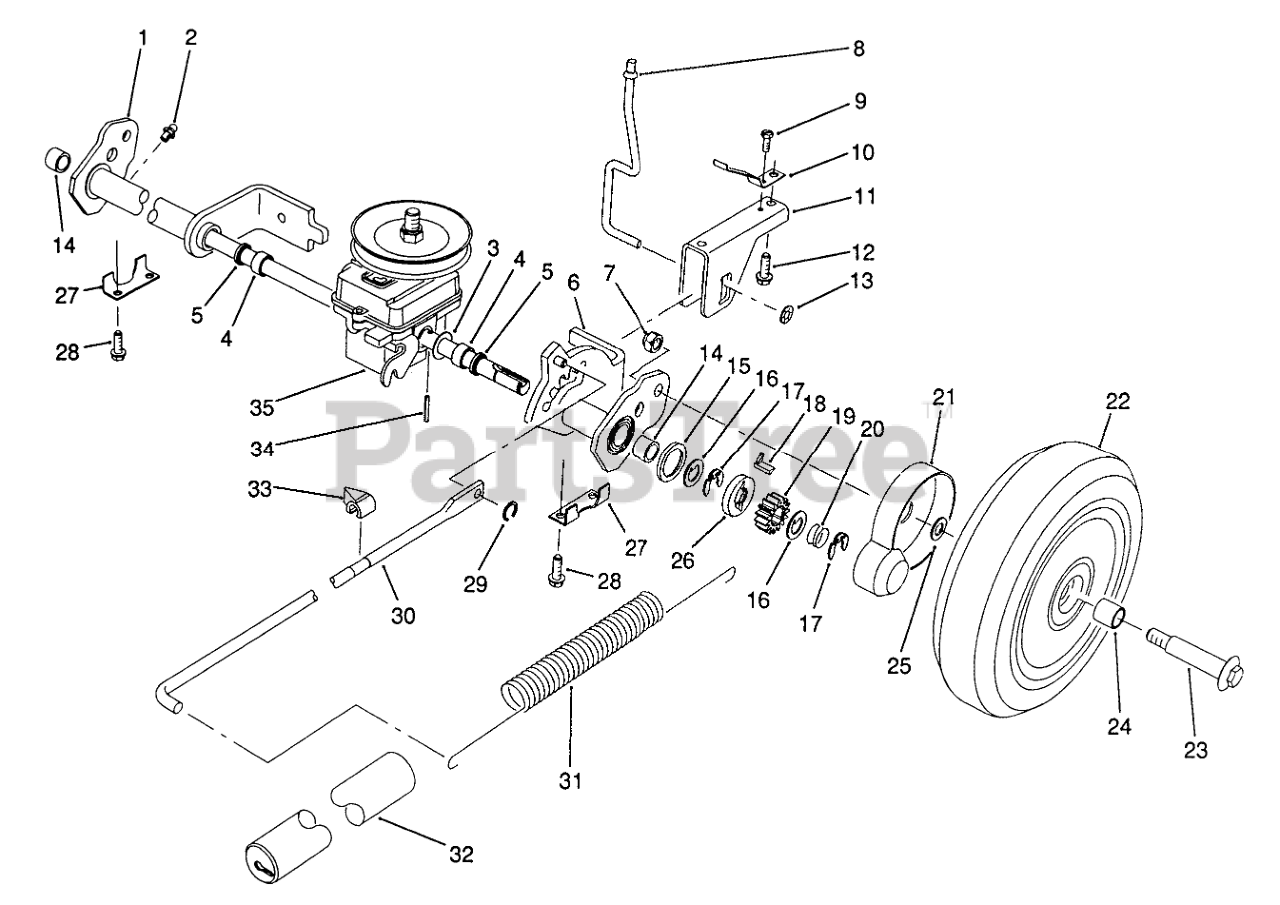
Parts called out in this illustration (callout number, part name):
1	Rear Pivot Assembly R.H. (Incl. Ref. #2, 4, 5 & 14)
2	Fitting-Grease
3	WASHER-PLAIN
4	BUSHING
5	SEAL-OIL
6	Rear Pivot Assembly L.H. (Incl. Ref. #2, 4, 5 & 14)
7	Nut
8	TRIGGER ROD
9	SCREW 8 - 32 X 250
10	SPRING - TRIGGER RET
11	SADDLE - HOC
12	SCREW
13	PUSHNUT
14	BEARING-ROLLER
15	RING-FRICTION
16	WASHER-THRUST, KEYED
17	RING-CLIP, LOCKING
18	KEY-ROCKING, LH
19	GEAR-PINION
20	SPRING-COMPRESSION
21	COVER-WHEEL
22	Wheel, Tire & Gear Assy. (Incl. Ref. #24)
23	BOLT-WHEEL
24	BUSHING
25	SPACER-COVER, WHEEL
26	WASHER-CLUTCH
27	REAR SECURING PLATE
28	SCREW-HWHTF
29	GRIP RING
30	LINK ROD
31	SPRING-COUNTERBALANCE
32	COVER-SPRING
33	INDICATOR-HEIGHT OF CUT
34	COIL PIN
35	Gearbox Assembly
